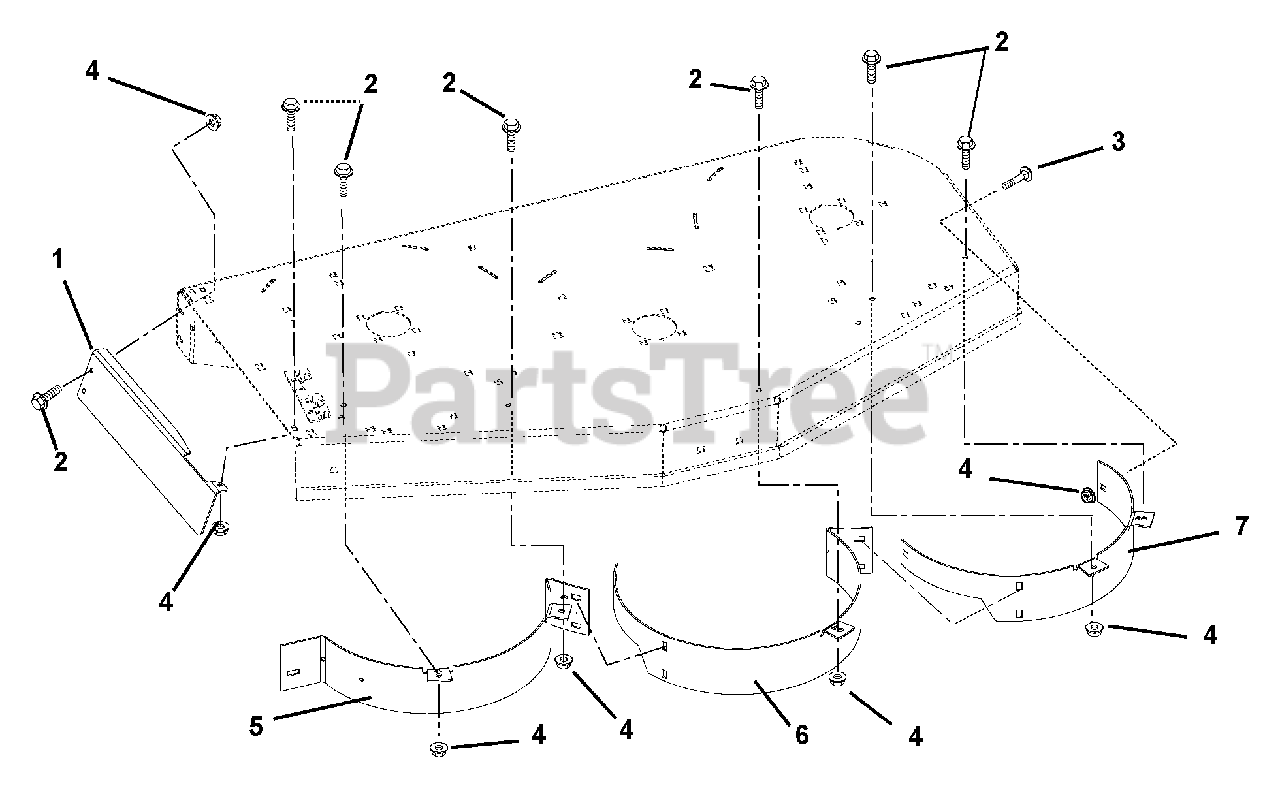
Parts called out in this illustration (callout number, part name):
1	BLOCK-OFF PLATE
2	BLT-SERHFWH .312-18X.75 YWZC
3	@BLT-RHDSSQNK .31-18X.75 G5YZ
4	@NUT-LK-NYL-FLG .31-18 YWZC
5	BAFFLE-MULCH-RIGHT FRONT-40"
5	BAFFLE-MULCH-RIGHT FRONT-44"
6	BAFFLE-MULCH-CENTER FRONT-40"
6	BAFFLE-MULCH-CENTER FRONT-44"
7	BAFFLE-MULCH-LEFT FRONT-40"
7	BAFFLE-MULCH-LEFT FRONT-44"
